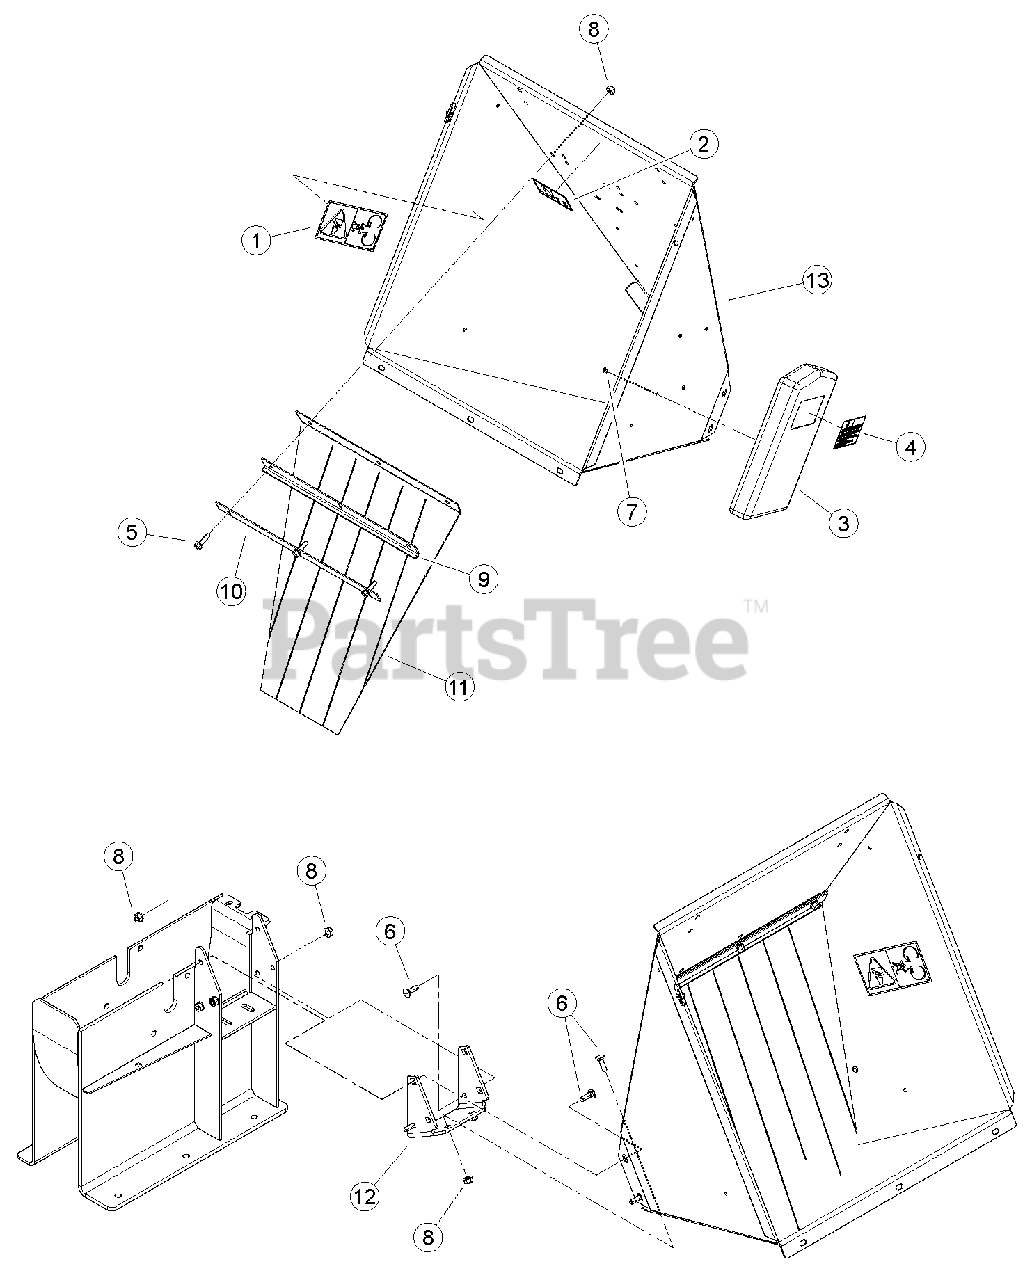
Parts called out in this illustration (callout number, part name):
1	DECAL, BLADE DANGER ISO
2	DECAL, MAINTENANCE ISO
3	CONTAINER, INSTR. MANUAL
4	DECAL, MUTILINGUAL MANUAL
5	BOLT, 3/8 X 1-1/4 FLANGE NC
6	BOLT, 3/8 X 1-1/4" GR5 CRG NC ZP
7	RIVET 1/4X1/2 DOME HD BLIND SS
8	NUT, 3/8-16 NYLOCK FLANGE
9	ANGLE, FLAP ANCHOR
10	STRIP, FLAP RETAINER
11	FLAP, CHIPPER CHUTE
12	BRACKET, CHUTE MOUNT
13	ASSEMBLY, 5 INCH CHIPPER CHUTE
